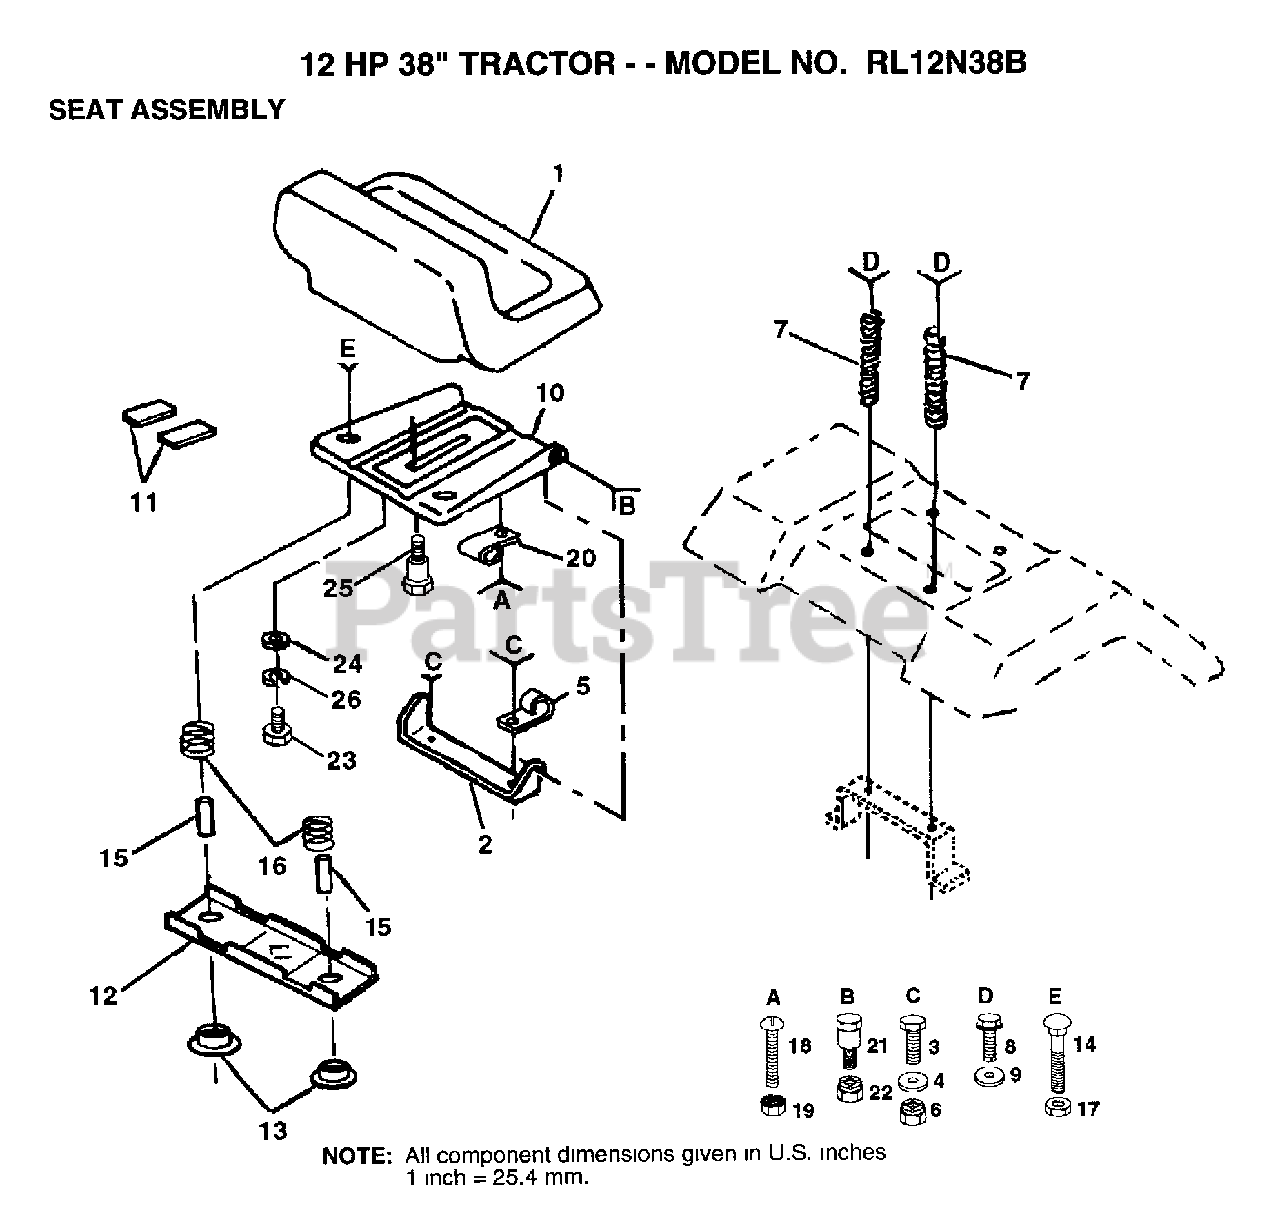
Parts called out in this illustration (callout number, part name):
4	WASHER PM
5	CLIP T
7	SPRING COMPRESSIO
8	SCREW GTV
9	WASHER
11	STRIP FORM
12	BRKT SWITCH
13	BUSHING
15	SPLIT SPACER
16	SPRING
19	"NUT,KEPS"
23	BOLT
24	WASHER
25	"BOLT,SHOULDER"
26	LOCKWASHER
